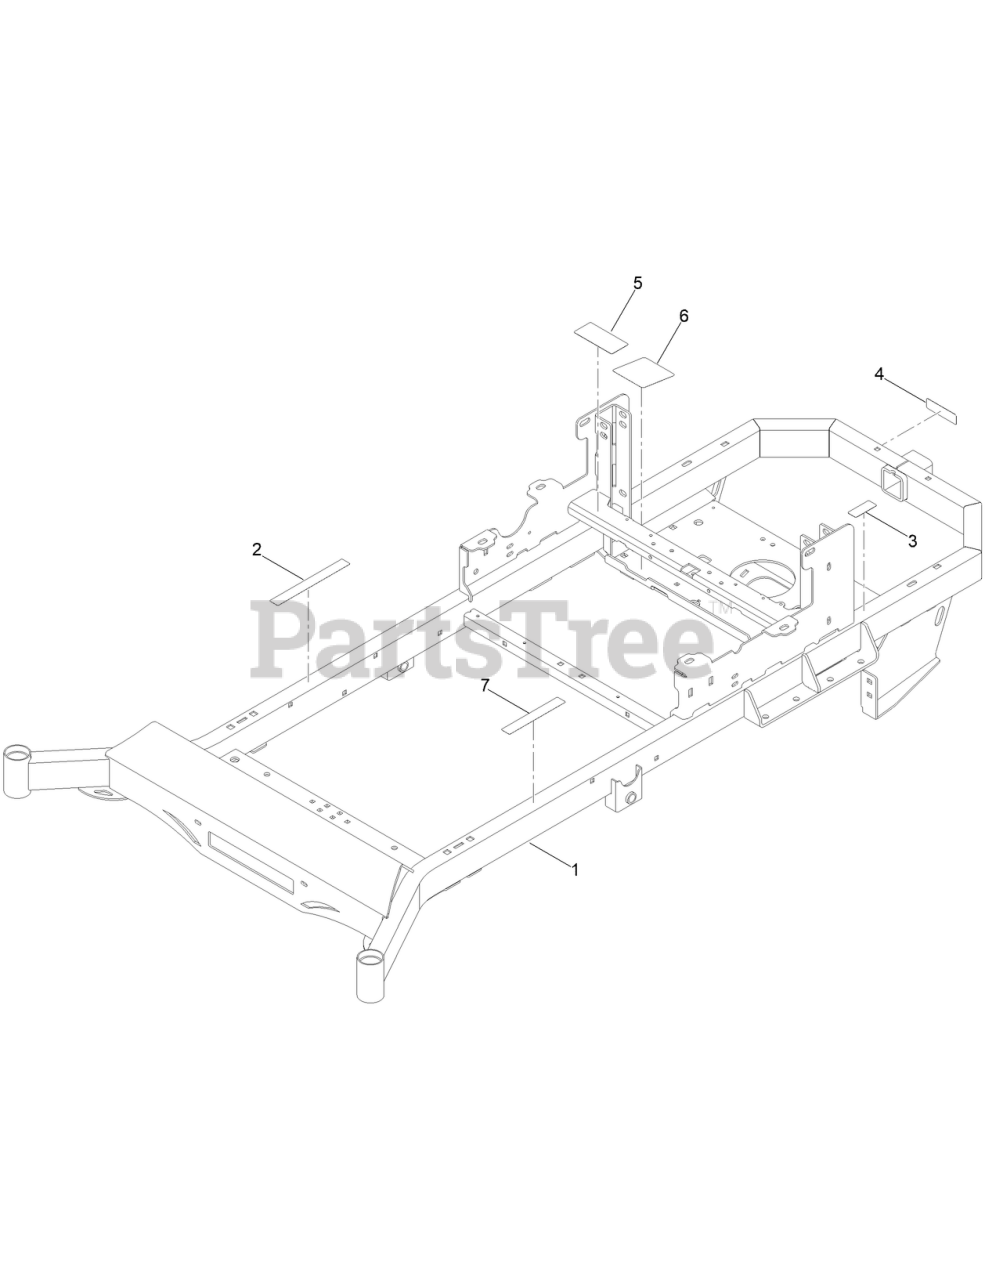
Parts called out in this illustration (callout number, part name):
1	FRAME-ZTR
2	DECAL-WARNING
3	DECAL-HOT SURFACE
4	DECAL-HITCH
5	DECAL-WARNING
6	DECAL-PUMP BELT ROUTING-PARKER
7	DECAL-WARNING
